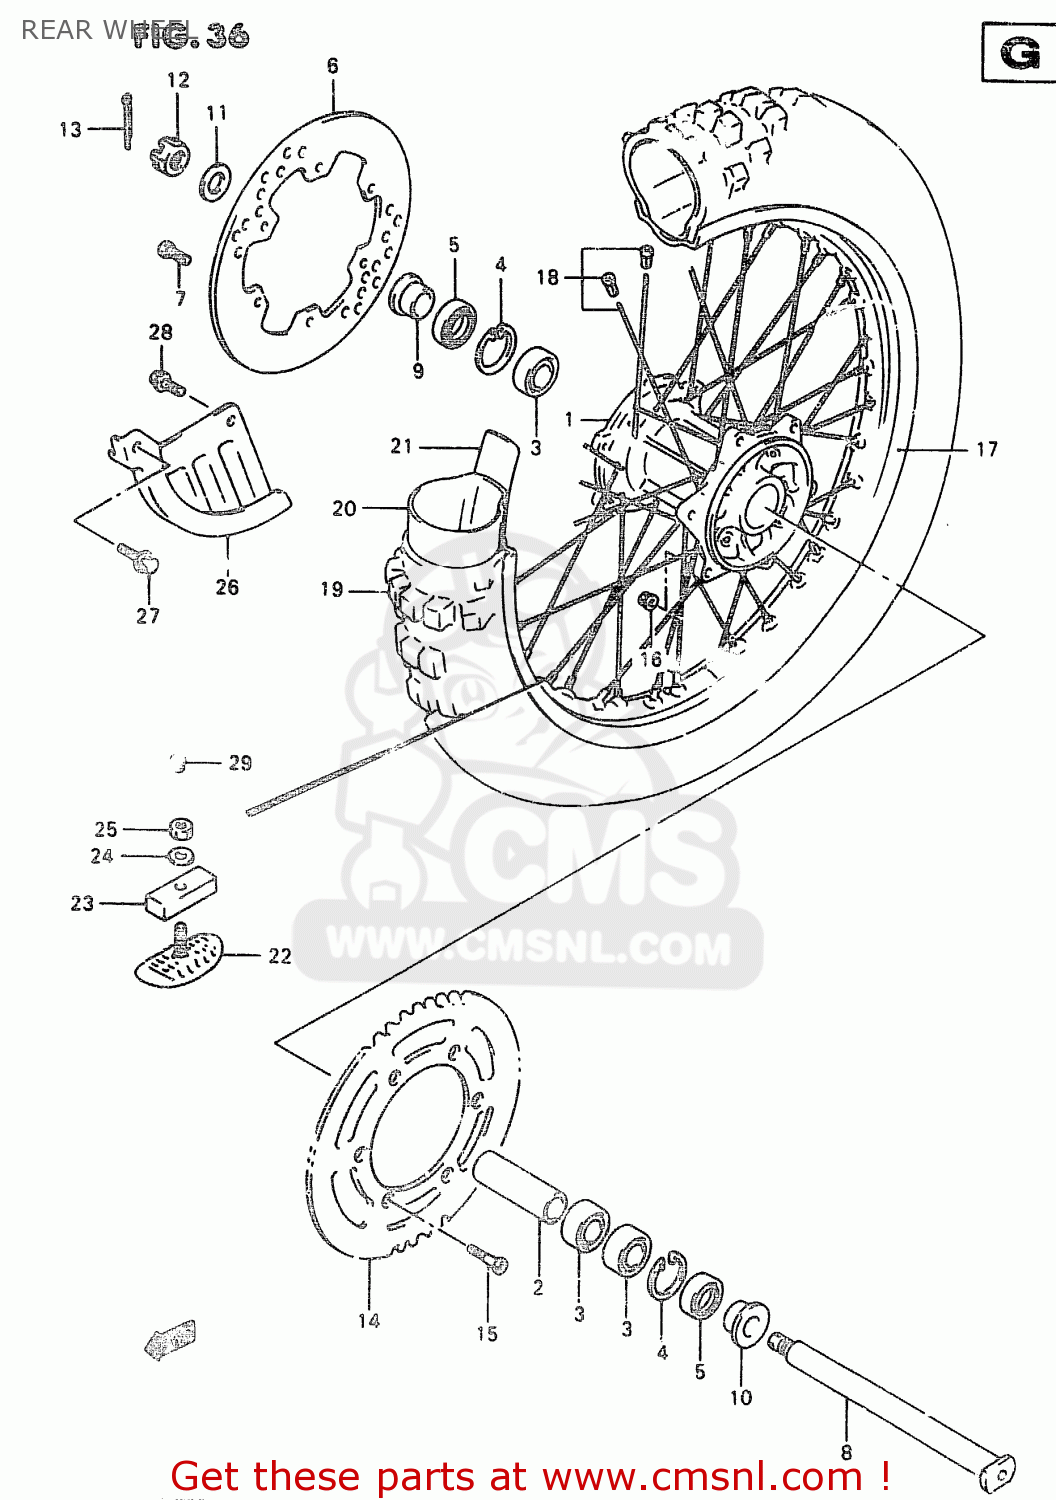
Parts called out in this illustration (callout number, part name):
1	HUB,RR WHEEL
2	SPACER,RR HUB BEARING
3	BEARING
4	CIRCLIP
5	SEAL(29X42X6)
6	DISC,RR BRAKE
7	SCREW
8	AXLE,RR
9	SPACER,RR AXLE
10	SPACER,RR AXLE
11	WASHER(19X32X3.2)
12	NUT
13	PIN,COTTER
14	SPROCKET,RR(NT:49)
15	BOLT(8X30.5)
16	NUT
17	RIM,RR WHEEL(2.15X19 AL)
18	SPOKE SET,RR WHEEL
19	TIRE,REAR 110/90-19
20	TUBE ASSY,WHEEL INNER
21	PROTECTOR,WHL INR TUBE
22	STOPPER,BEAD(2.15)
23	CUSHION,BEAD STOPPER
24	WASHER
25	NUT
26	COVER SET,RR BRAKE DISC
27	BOLT
28	BOLT
29	CAP(OD:12)
